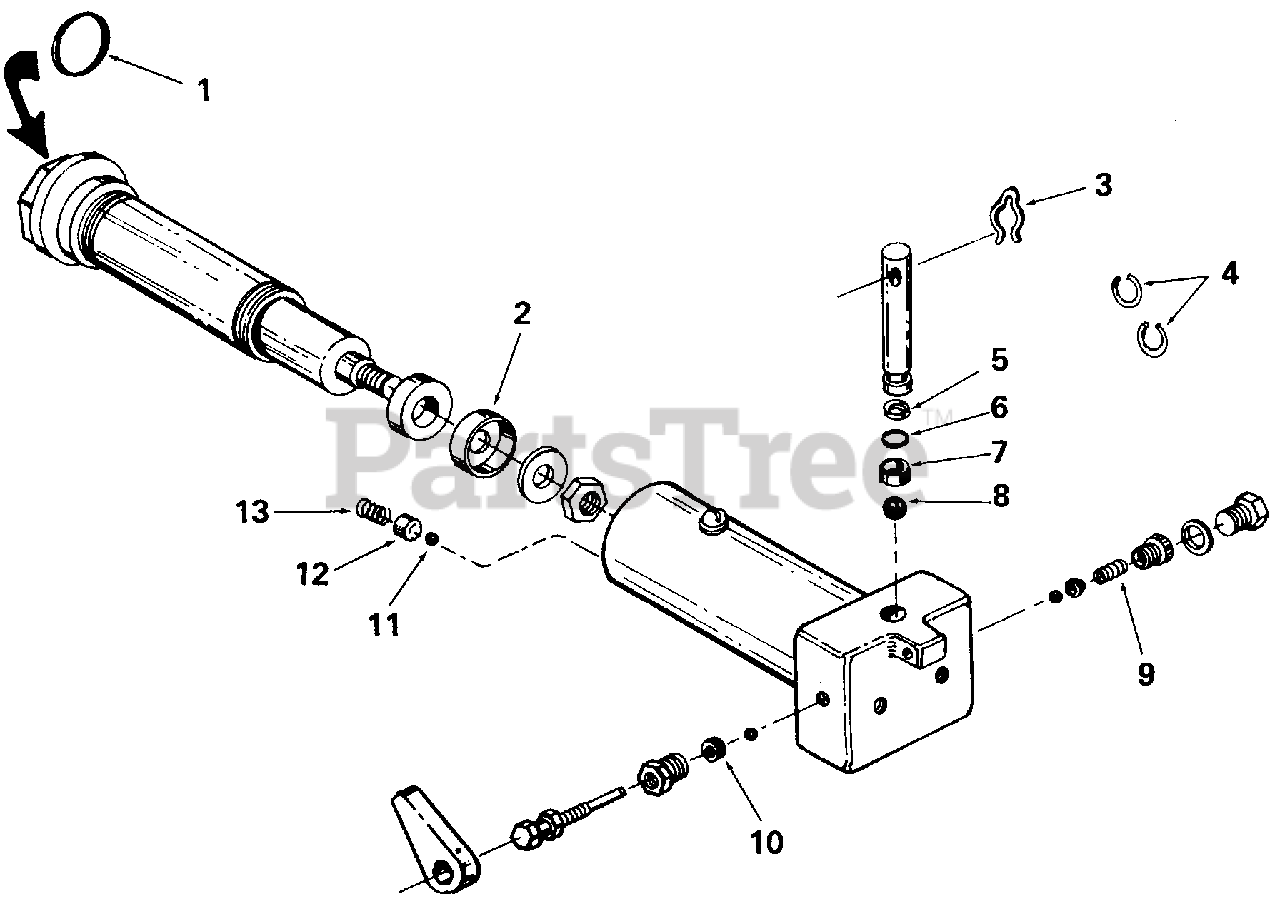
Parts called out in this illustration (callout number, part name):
1	Quad Ring
2	Cup
3	Hair Pin Clip
4	Pin Ring
5	Back-Up Washer
6	"O"-Ring
7	Ball Retainer
8	Ball
9	Spring
10	Packing
11	Ball
12	Ball Retainer
13	Spring
